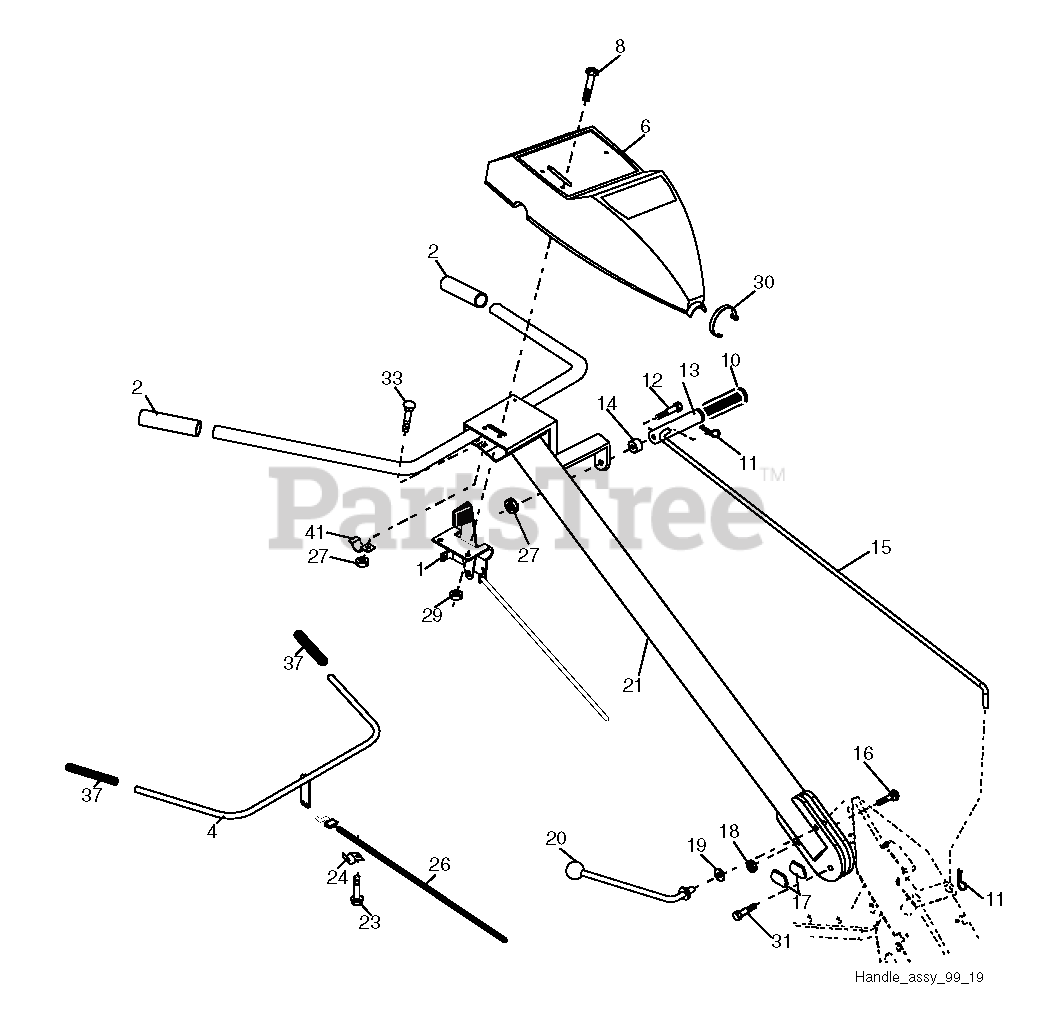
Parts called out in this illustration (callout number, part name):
1	THROTTLE.CONTROL.RT.INTEK.50
2	KIT.GRIP.HANDLE.5.00.BLK.VINYL
4	CONTROL BAR ASSY
6	RP CONTROL PANEL
8	SCREW.PNHD.10-24
10	GRIP T
11	RETAINER M
12	SHOULDER BOLT ST
13	HANDLE.SHIFT.TILLER
14	GROMMET.RUBBER.CRT.TILLER
15	SHIFT ROD CRT
16	BOLT D
17	LOCK.HANDLE.CRT
19	WASHER CRT
20	LEVER.LOCK.CRT
21	REPL BY 532 1805-17
23	TAPPING SCREW
24	CONDUIT.CLIP.PLATED
26	CABLE.CLUTCH
27	NUT T
29	NUT **
30	TIE CABLE CRT
31	BOLT.PIVOT
37	GRIP BAR CRT(1)
41	CLAMP.BAR.CRT.BLACK
